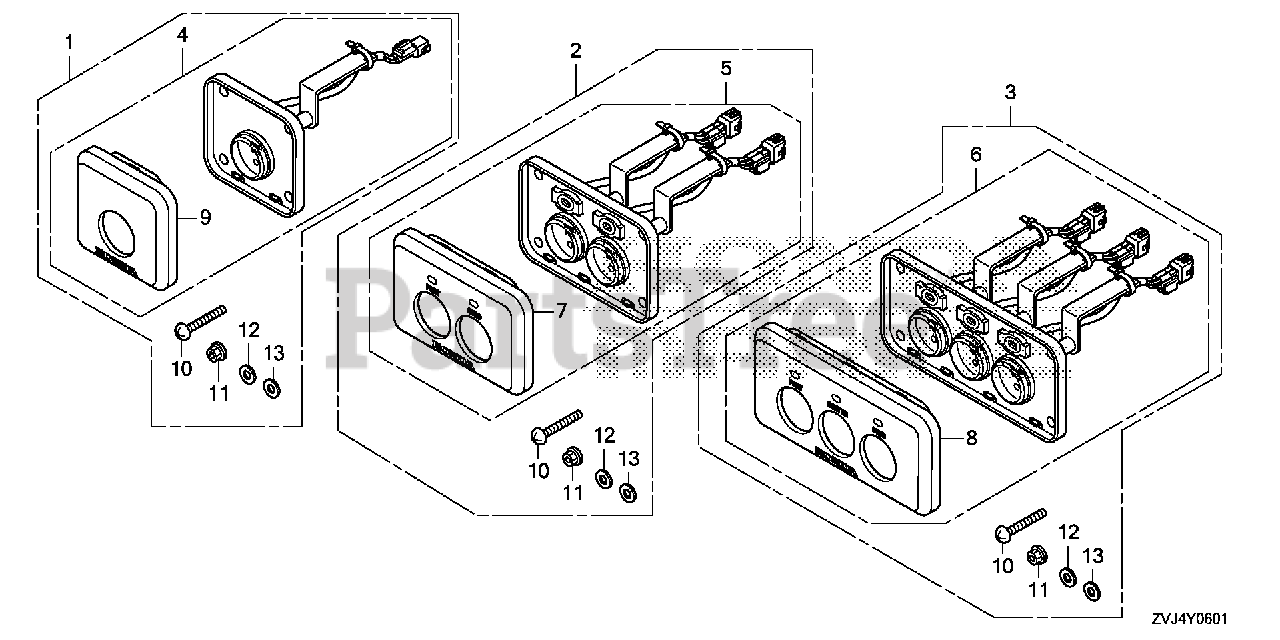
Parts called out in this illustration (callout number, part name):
1	PANEL KIT, START STOP SWITCH (ALL)
2	PANEL KIT, START STOP SWITCH (TWIN)
3	PANEL KIT, START STOP SWITCH (TRIPLE)
4	PANEL ASSY., START STOP (ALL)
5	PANEL ASSY., START STOP (TWIN)
6	PANEL ASSY., START STOP (TRIPLE)
7	PANEL, START STOP (TWIN)
8	PANEL, START STOP (TRIPLE)
9	PANEL, START STOP (ALL)
10	SCREW, PAN (5X40)
11	NUT, FLANGE (5MM)
12	WASHER, PLAIN (5MM)
13	WASHER, SPRING (5MM)
